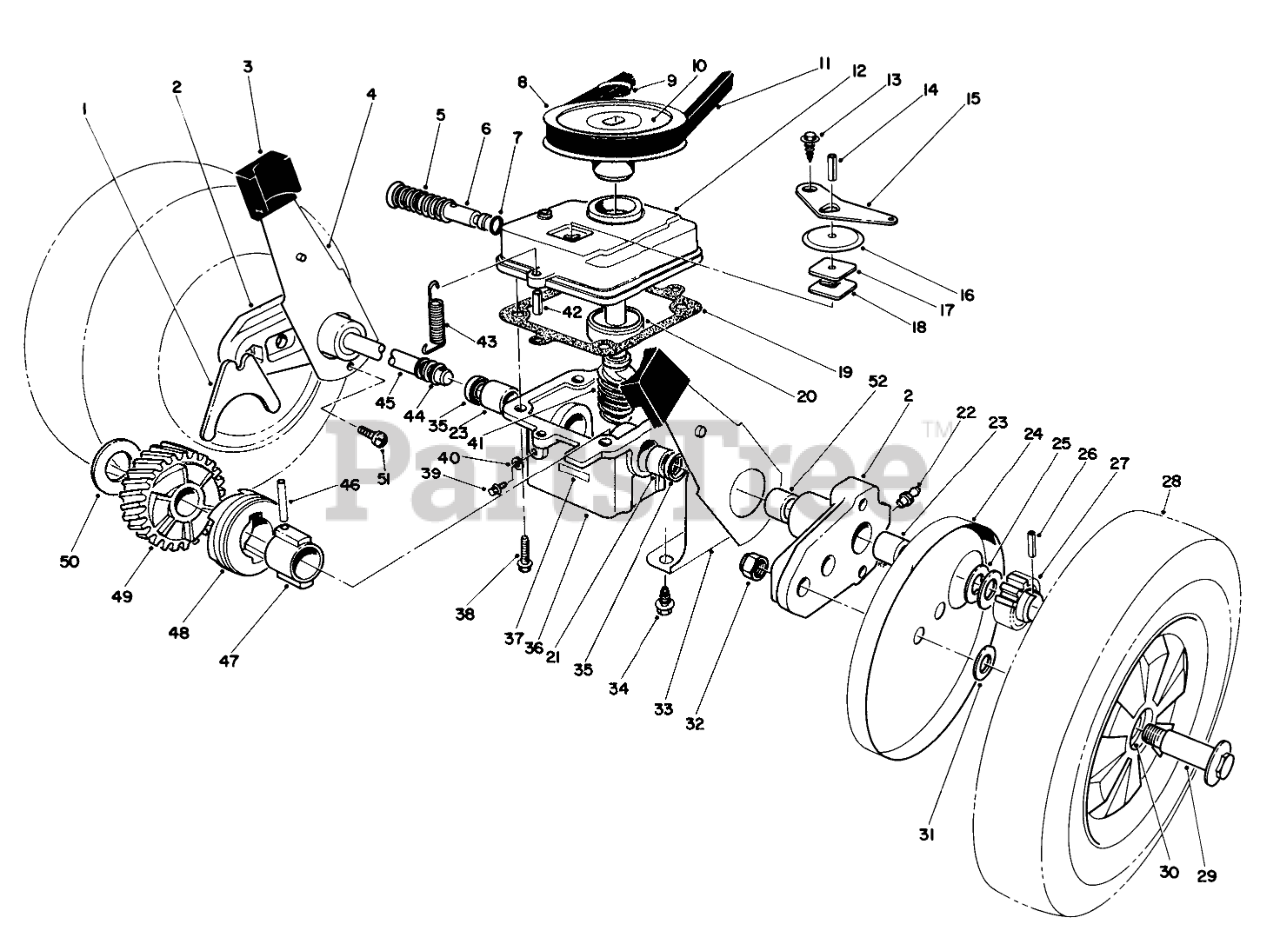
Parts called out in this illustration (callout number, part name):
1	SHIFTER FORK
2	Arm-Pivot (Incl. Ref. #22, 23 & 52)
3	KNOB-ARM
4	SPRING ARM ASSY-FRONT
5	SPRING
6	SHIFTER ROD
7	O-RING
8	PULLEY
9	PUSH-ON 93-3236
10	DECAL
11	V BELT
12	GEAR CASE COVER
13	Screw
14	SPIROL PIN H D
15	SHIFTER ARM
16	DUST COVER
17	DUST FILTER
18	LATCH PLATE
19	GASKET
20	BEARING
21	BUSHING
22	FITTING-GREASE
23	BUSHING
24	Cover-Wheel
25	THRUST WASHER
26	Pin
27	PINION GEAR 15T
28	Wheel, Tire, & Gear Assembly (Incl. Ref. #30)
29	BOLT-WHEEL
30	BUSHING
31	WASHER
32	Nut
33	END CAP
34	SCREW-HWHTF
35	SEAL-OIL
36	Gear Case (Incl. Ref. #21, 23, & 35)
37	DECAL
38	Screw
39	NYLON SCREW
40	FILL PLUG GASKET
41	Worm Shaft & Gear (Incl. Ref. #49)
42	3/16 X 1/2 ROLL PIN
43	TENSION SPRING
44	COVER-SHAFT, DRIVE
45	DRIVE SHAFT
46	COIL PIN
47	SLEEVE
48	CLUTCH JAW
49	Helical Gear
50	THRUST WASHER
51	SCREW
52	BUSHING
